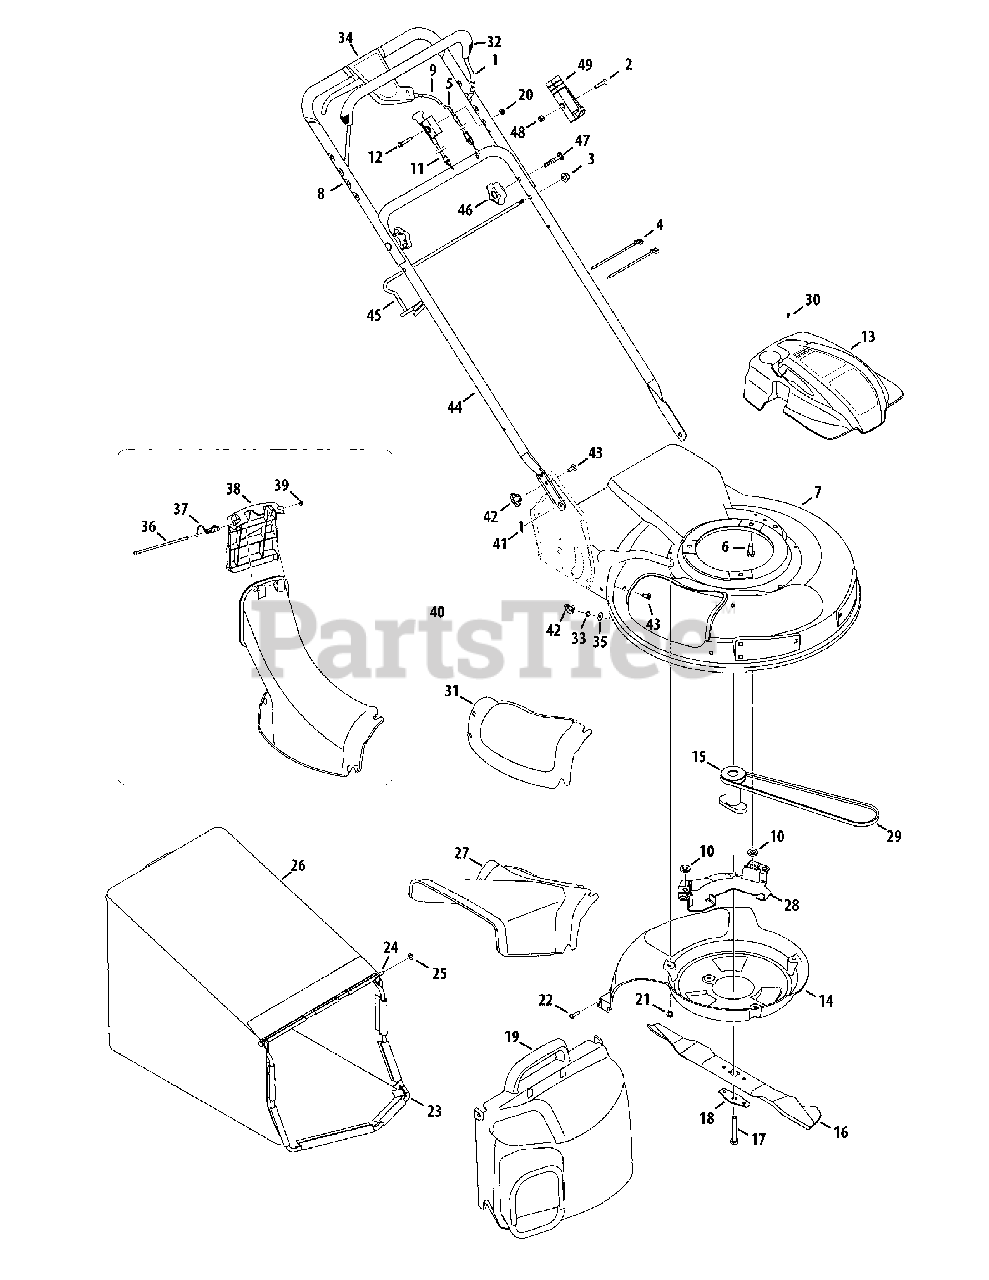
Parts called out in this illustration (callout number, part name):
2	Machine Screw, 1/4-20 x 1.310
3	Flange Lock Nut, 5/16-18
4	Cable Tie
5	Control Cable
6	TT Screw, 3/8-16 x 1.00
9	Drive Cable
10	Washer, Flat, .407 x .812 x .135
11	Choke Cable
12	Screw, 1/4-20 x 1.50
13	Engine Shroud
14	Rear Baffle
15	Blade Adapter
16	21-inch Mulching Blade
17	HH Cap Screw, 3/8-24 x 2.50
18	Bell Blade Spacer
19	Grass Bag Cover Assembly
20	Flange Lock Nut 1/4-20
21	TT Screw 1/4-20 x .375
22	HL Screw 1/4-15 x .75
24	Grass Bag Pivot Rod
25	Cap Speed Nut
26	Grass Bag Assembly
27	Side Discharge Chute
28	Belt Keeper
29	V-Belt
30	Screw, #12-16 x 1.00
31	Mulch Cover
32	Bail Cover
34	Drive Control Assembly
35	Washer, Flat, .260 x .720 x .060
36	Chute Door Pivot Rod
37	Torsion Spring
38	Top Discharge Door Chute
40	Top Discharge Chute Assembly
41	Cotter Pin
42	Wing Nut
43	Carriage Screw 1/4-20 x .75
46	Star Knob
47	Carriage Bolt 5/16-18 x 2
48	Hex Lock Nut 1/4-20
49	ERS Housing
